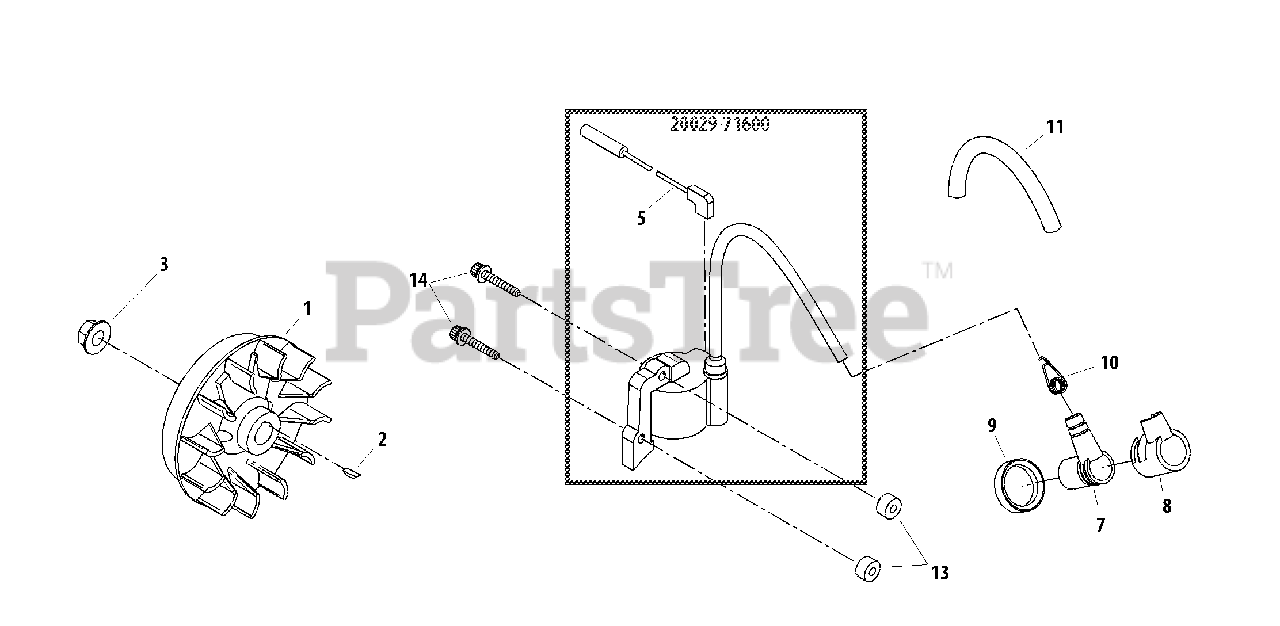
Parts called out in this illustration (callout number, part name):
1	FLYWHEEL
2	KEY - 3X10
3	NUT - 8
5	LEAD - IGNITION
7	CAP, SPARK PLUG
8	CAP, SPARK PLUG
9	SEAL, DUST
10	TERMINAL, SPARK PLUG CAP
11	TUBE
13	INSULATOR
14	SCREW - 4X26
20029-71600	IGNITION COIL ASSY
